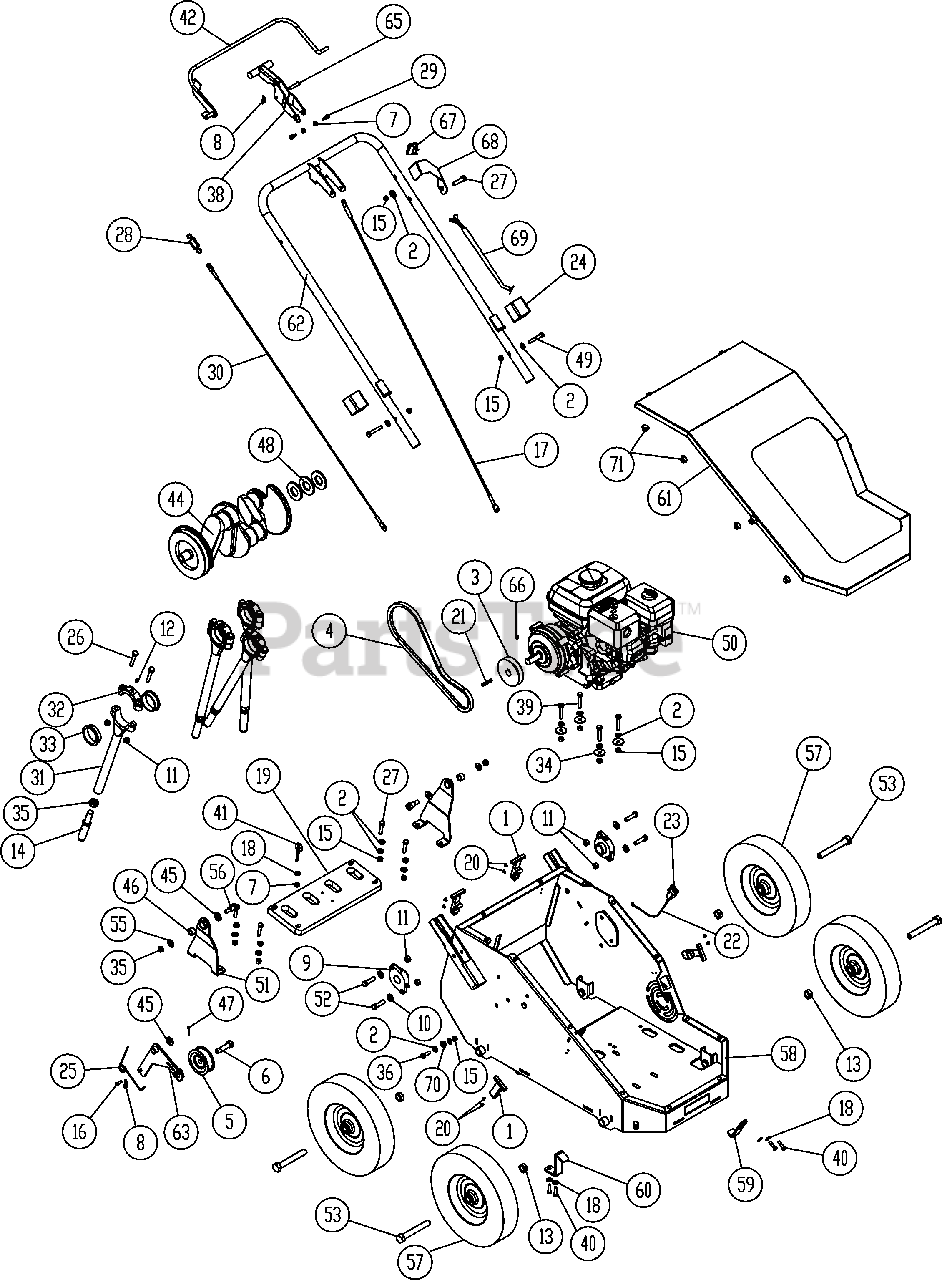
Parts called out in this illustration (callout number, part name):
1	RUBBER LATCH KIT
2	FLAT WASHER 5/16"
3	ENGINE PULLEY 3.5"
4	COGGED V-BELT B 35"
5	IDLER PULLEY 2.75" DIA
6	SCREWCAP 3/8" - 16 x 1 1/2" GR 5 ZP
7	NYLOCK NUT 1/4"- 20 UNC
8	1/4" RUE RING
9	CARTRIDGE BEARING 1" DIA
10	3/8" FLAT WASHER
11	NUTLOCK 3/8-16
12	ZERK FITTING GREASE
13	NUT JAM 5/8"-11 2 WAY LOCKNUT ZP
14	TINE 5/8" DIA
15	NUTLOCK 5/16"-18
16	CLEVIS PIN 1/4" X 3/4"
17	RETRACTOR PLATE CABLE
18	WASHER 1/4" FLAT
19	400 SERIES RETRACTOR PLATE
20	STAINLESS RIVET 1/8" X 1/4"
21	KEY 3/15" SQ X 1 1/4
22	WIRE HARNESS PL HOOD SWITCH
23	SWITCH INTERLOCK
24	HANDLE LOCK SLEEVE
25	CLUTCH TORSION SPRING
26	SCREWCAP 3/8'-16 X 2"
27	SCREWCAP 5/16"-18 X 1 1/2"
28	EXTENSION SPRING 3/4" X 1" - 3"
29	SOCKET HEAD SHOULDER BOLT 5/16" X 1/4"
30	CLUTCH CABLE 37"
31	TINE ROD
32	TINE ROD CAP
33	JOURNAL BEARING 2"
34	FENDER WASHER 5/16"
35	NUT JAM 5/8"-11 ZP
36	SCREWCAP 5/16"-18 X 1" HCS ZP
37	RETRACTOR PLATE LATCH
38	RETRACTOR HANDLE
39	SCREWCAP 5/16"-18 X 1 3/4" HCS ZP
40	SCREWCAP 1/4"-20 X 3/4" GR 5 HCS ZP
41	EYEBOLT 1/4" - 20
42	400 SERIES CLUTCH LEVER
44	4 TINE CRANK
45	WASHER 1/2" FLAT
46	BUSHING 1/2" ID X 3/4" OD X 1/2"
47	COTTER PIN 1/8" X 1"
48	MACHINERY BUSHING 1" X 1 1/2" X 14 GA
49	SCREWCAP 5/16"-18 X 2" HCS ZP
50	BRIGGS VANGUARD ENGINE W/GEARBOX
51	RETRACTOR PLATE ARM
52	SCREWCAP 3/8"-16 X 1 1/2" HCS ZP
53	SCREWCAP 5/8"-11 X 4 1/2" HCS ZP
55	WASHER 5/16" USS THRU-HARDENED ZINC YELLOW
56	SHOULDER BOLT 1/2" X 5/8"
57	WHEEL 12" SEMI-PNEUMATIC W/ 5/8" BEARING HUB
58	400 SERIES FRAME
59	UPPER BELT TENSIONER BRACKET
60	LOWER BELT TENSIONER BRACKET
61	COVER WA PL18
62	400 SERIES HANDLE
63	CLUTCH ARM
64	PL1800 DECAL KIT
65	PIN CLEVIS 1/4" X 1 1/8" ZP
66	SCREW SET 5/16"-18 X 5/16" TORQUE TO 22-24 FT-LBS.
67	SWITCH LKG RKR
68	BRACKET MOUNT SWITCH
69	HARNESS WIRE 60"
70	NUT 5/16" - 18 SER HEX WSHR FLNG ZP
71	RUBBER BUMPER PUSH IN
